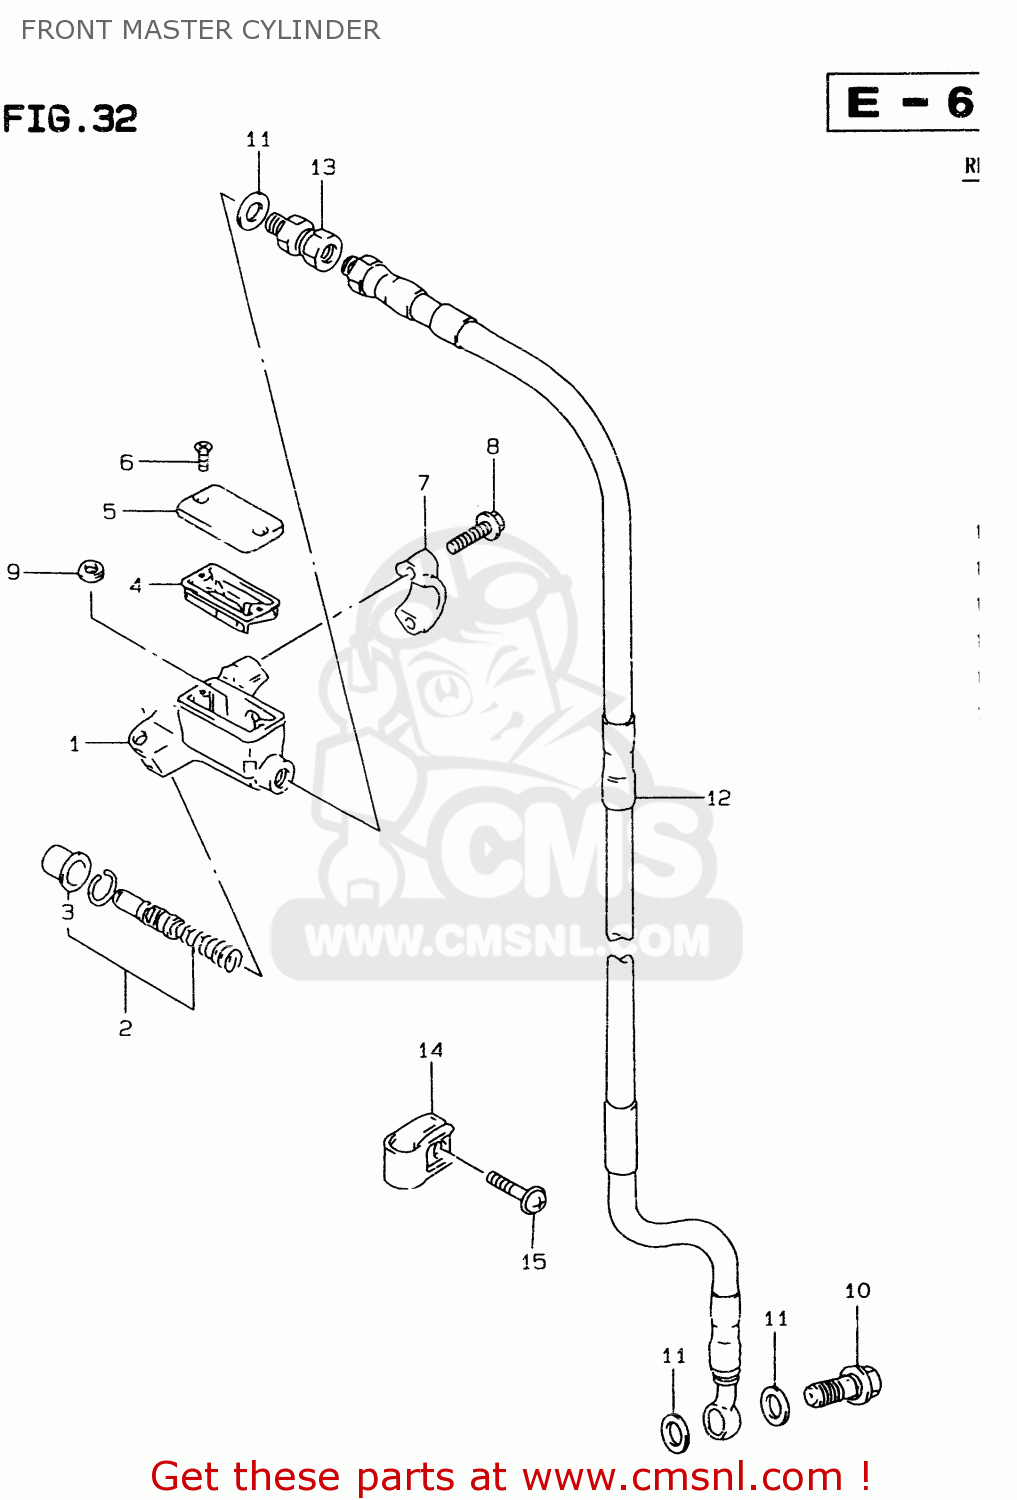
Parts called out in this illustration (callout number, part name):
1	CYLINDER ASSY,FR MASTER
2	PISTON & CUP SET
3	BOOT
4	DIAPHRAGM
5	CAP
6	SCREW
7	HOLDER
8	BOLT
9	SEPARATOR
10	BOLT UNION
11	WASHER(10X15X1.5)
12	HOSE,FR BRAKE
13	ADAPTOR,BRAKE HOSE
14	CLAMP,FR BRAKE
15	SCREW
